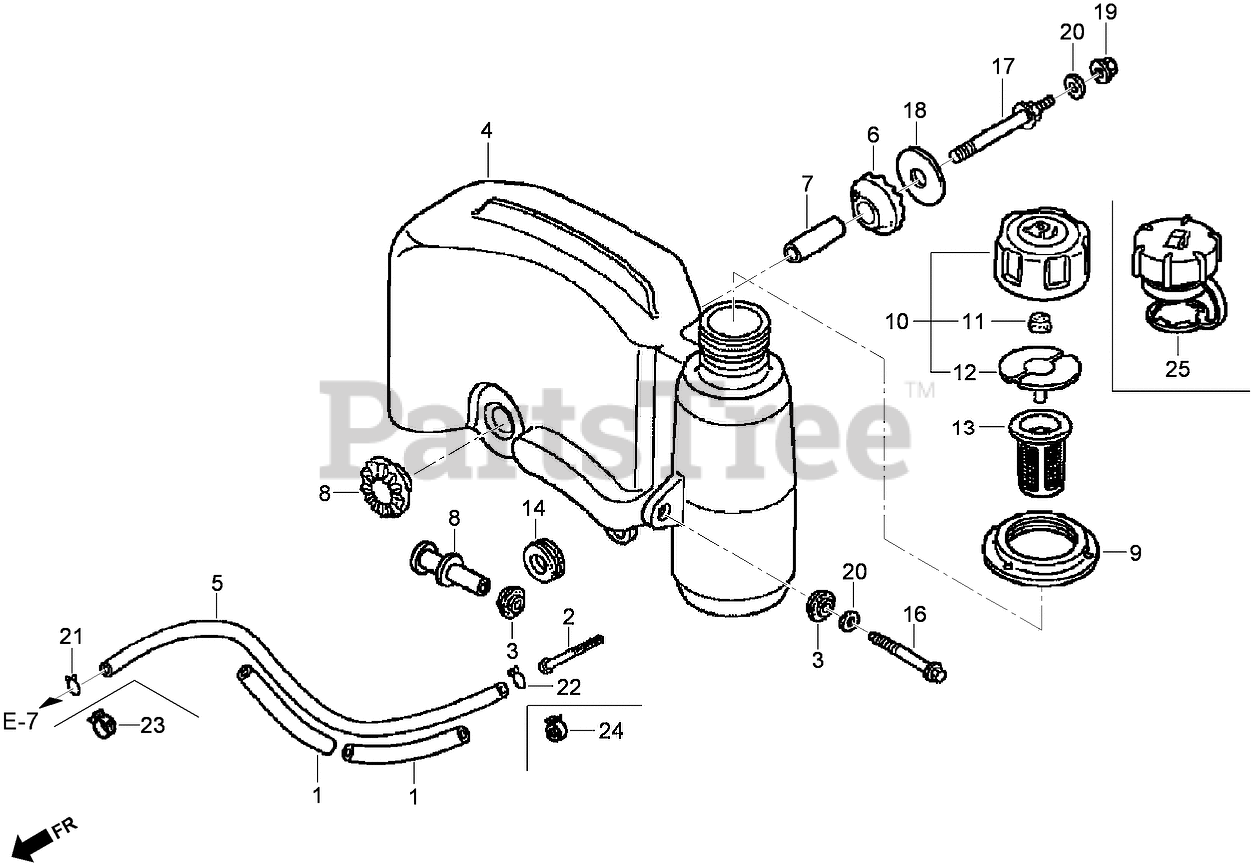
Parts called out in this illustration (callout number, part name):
1	SUPPORTER-RUBBER (107 mm)
2	FILTER-FUEL
3	RUBBER-SETTING, TANK
4	TANK-FUEL (Engine Serial No. Up To 1036455)
4	TANK-FUEL (Engine Serial No. From 1036456)
5	TUBE-FUEL (Engine Serial No. Up To 1011283)
5	TUBE-FUEL (FKM) (Engine Serial No. From 1011284)
6	RUBBER B-MOUNTING, TANK
7	COLLAR-SET, TANK
8	COLLAR-TANK
9	RUBBER-MOUNTING, TANK (Engine Serial No. Up To 1036455)
10	FUEL TANK CAP ASM (Engine Serial No. Up To 1036455)
11	SPONGE-BREATHER, FUEL CAP (Engine Serial No. Up To 1036455)
12	GASKET-CAP, FUEL (Engine Serial No. Up To 1036455)
13	GAUGE-LEVEL, FUEL
14	CUSHION-FENDER, R R
16	BOLT-FLANGE (6X47) (C T200)
17	BOLT-STAY, TANK
18	WASHER-MOUNTING, TANK
19	NUT-FLANGE (6 mm)
20	WASHER-PLAIN (6 mm)
21	CLIP-TUBE (B8) (Engine Serial No. Up To 1011283)
22	CLIP-TUBE (C11) (Engine Serial No. Up To 1011283)
23	CLAMP-TUBE (D8) (Engine Serial No. From 1011284)
24	CLAMP-TUBE (D105) (Engine Serial No. From 1011284)
25	FUEL TANK CAP ASM (Engine Serial No. From 1036456)
